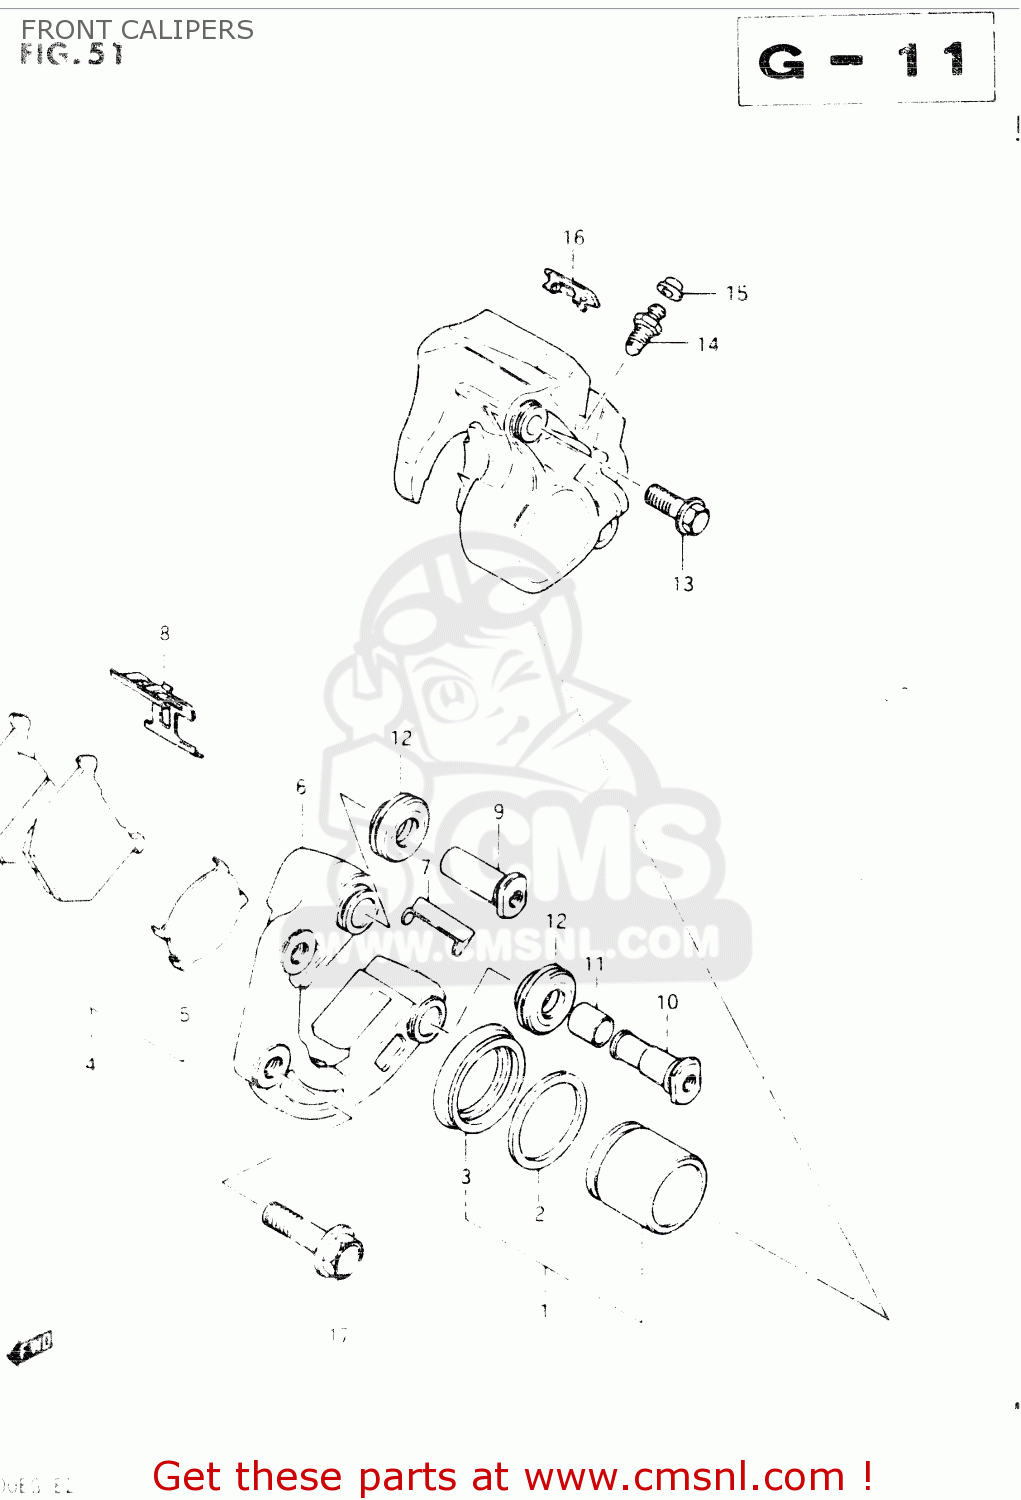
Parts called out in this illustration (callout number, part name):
1	PISTON SET
2	SEAL,FR CALIPE
3	BOOT,PISTON
4	PAD SET,BRAKE (MCA)
5	SHIM,PAD
6	CARRIER,CALIPER,LEFT
7	GUIDE,PAD
8	SPRING,PAD
9	AXLE NO.1
10	AXLE NO.2
11	BUSH,AXLE
12	BOOT,AXLE
13	BOLT
14	BLEEDER
15	CAP,BREATHER
16	COVER
17	BOLT 10X37
